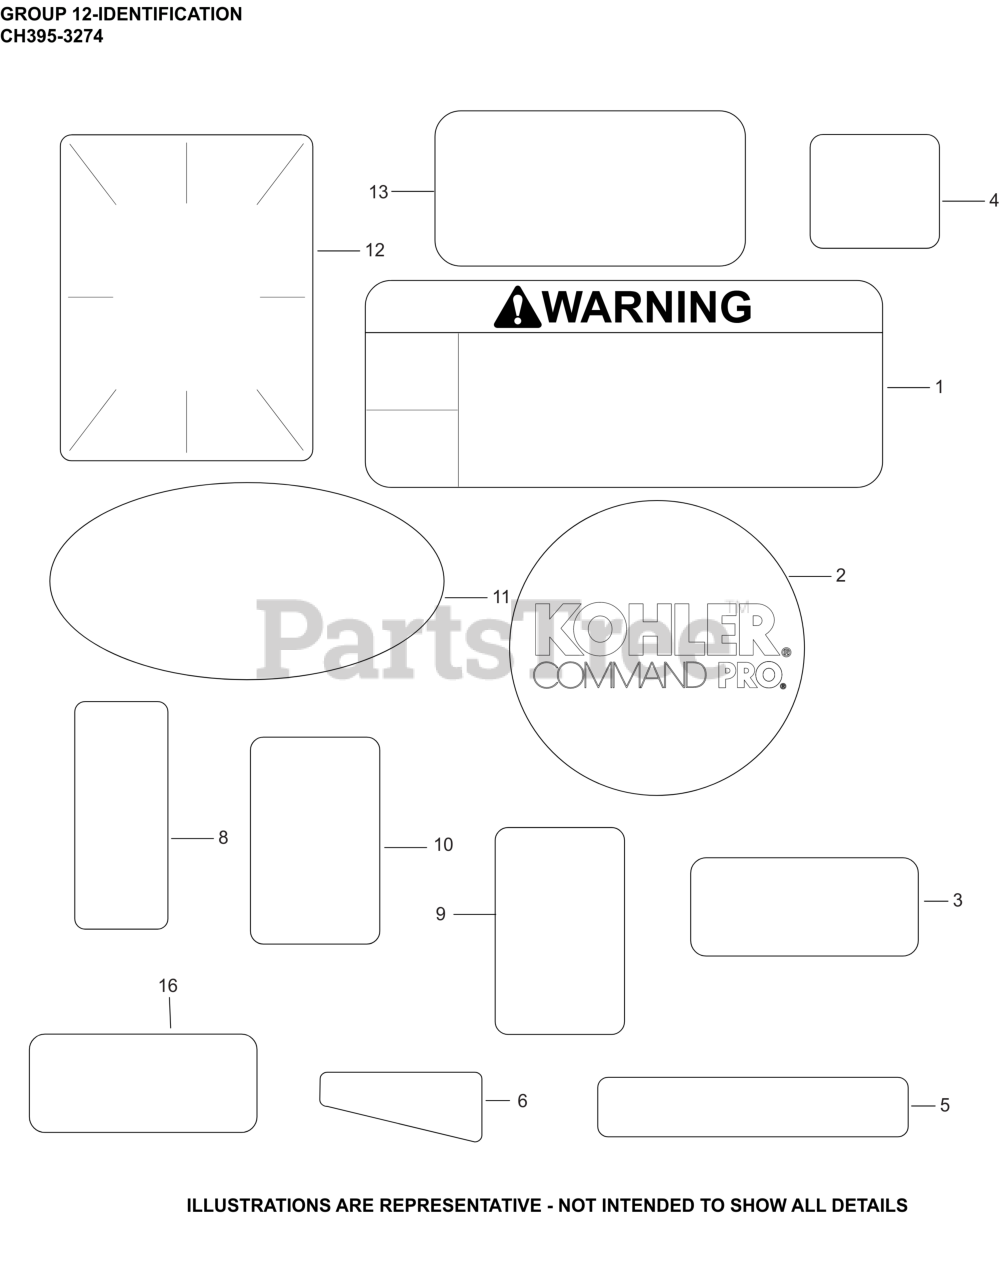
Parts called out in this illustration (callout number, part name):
1	DECAL, WARNING
2	LABEL, RECOIL 75MM
3	LABEL, CANADIAN COMPLIANCE
4	DECAL, BASE ARROW
5	DECAL, THROTTLE
6	DECAL, 9.5 HP/277cc/CH395
8	DECAL, FUEL/CHOKE - ON/OFF
9	DECAL, SUN
10	DECAL, SNOW FLAKE
11	DECAL, QUAD CLEAN SILVER
12	LABEL, CLEAR LAMINATION
13	LABEL, MAINTENANCE (CKY)
16	DECAL, ETHANOL WARNING
